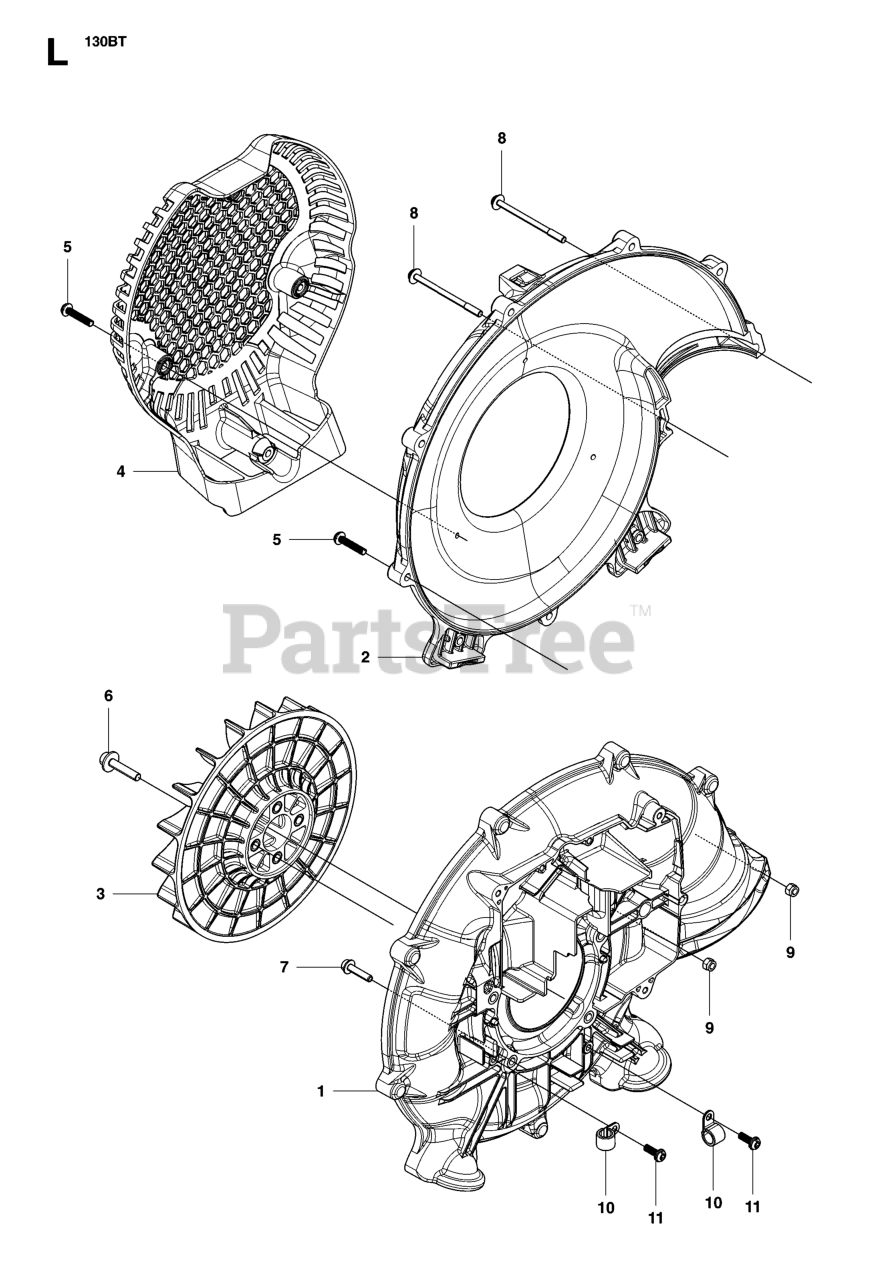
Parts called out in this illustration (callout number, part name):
1	VOLUTE CASE
2	COVER - VOLUTE
5	SCREW
7	BOLT
9	NUT
11	SCREW
